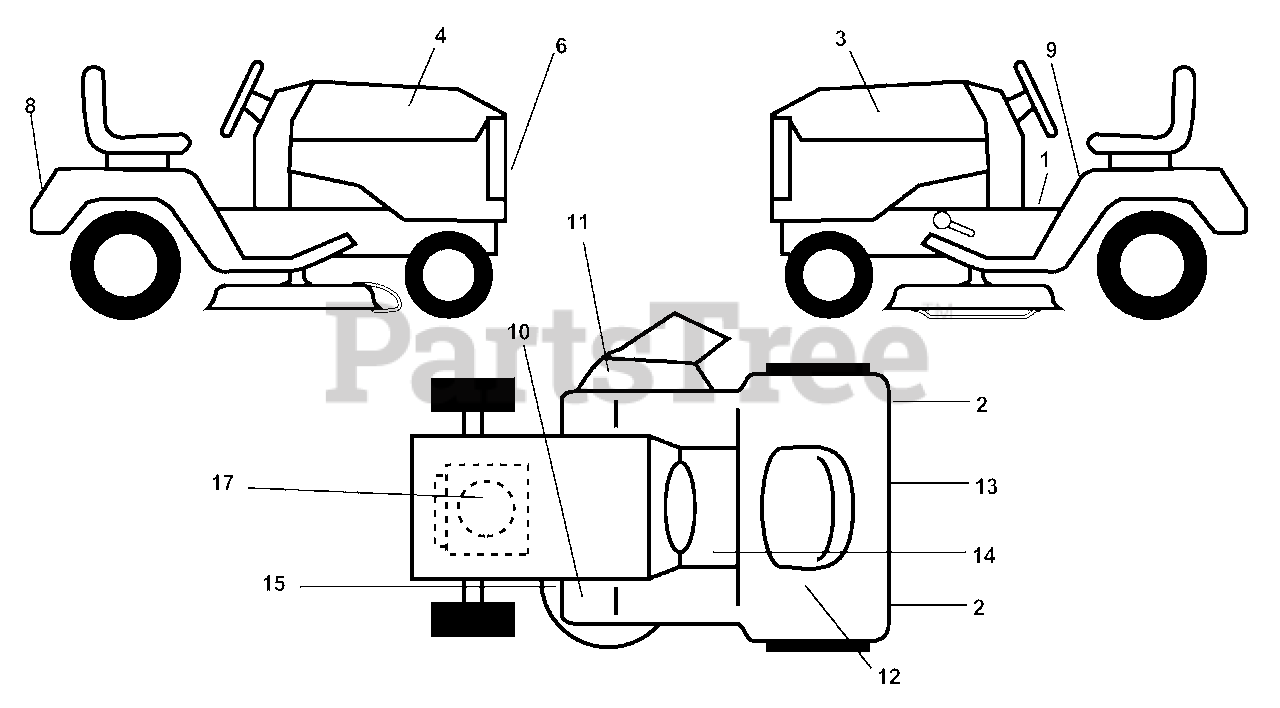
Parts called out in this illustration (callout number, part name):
1	Decal Instruction Dash Eng/fr
2	Reflector Taillight Red/Ambus
3	Decal Hood LH
4	Decal Hood RH
6	Decal Grille
8	Decal Fender Logo
9	Decal Caution Fender Eng/fr
10	Decal Clutch/brake Eng/fr
11	Decal Warning Multi-Language
12	Decal Bat Dan/Poi P/L Sym WPN
13	Decal Drawbar CNTRL MVT HYD LT
14	Decal SDL COLD START HYD E/F
15	Decal V-Belt Schematic
17	Decal Engine Kohler 15 HP
